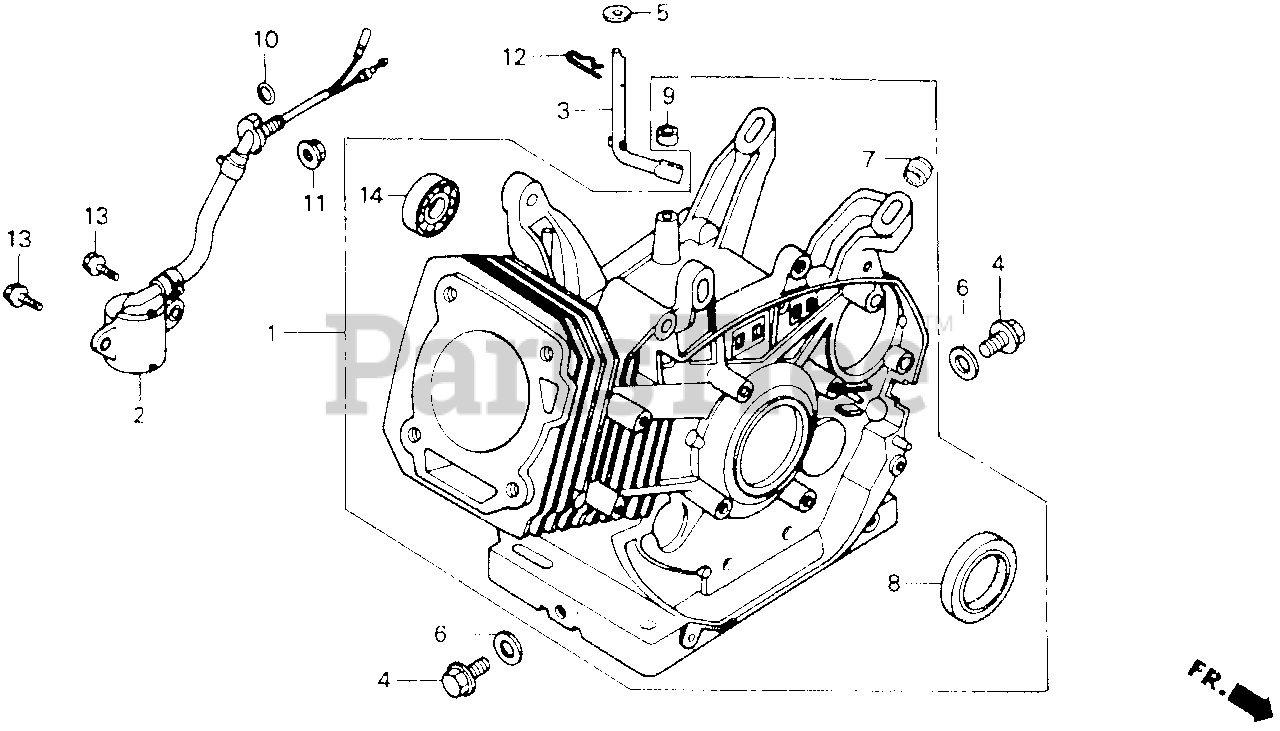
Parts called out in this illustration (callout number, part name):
1	CYLINDER ASSY. (ALERT)
2	SWITCH ASSY., OIL LEVEL
3	SHAFT, GOVERNOR ARM
4	BOLT, DRAIN PLUG
5	WASHER (8.2X17X0.8)
6	WASHER, DRAIN PLUG (12MM)
8	OIL SEAL (35X52X8)
9	OIL SEAL (8X14X5)
10	O-RING (13.5X1.5) (ARAI)
11	NUT, FLANGE (10MM)
12	PIN, LOCK (8MM)
13	BOLT, FLANGE (6X12)
14	BEARING, RADIAL BALL (6202)
